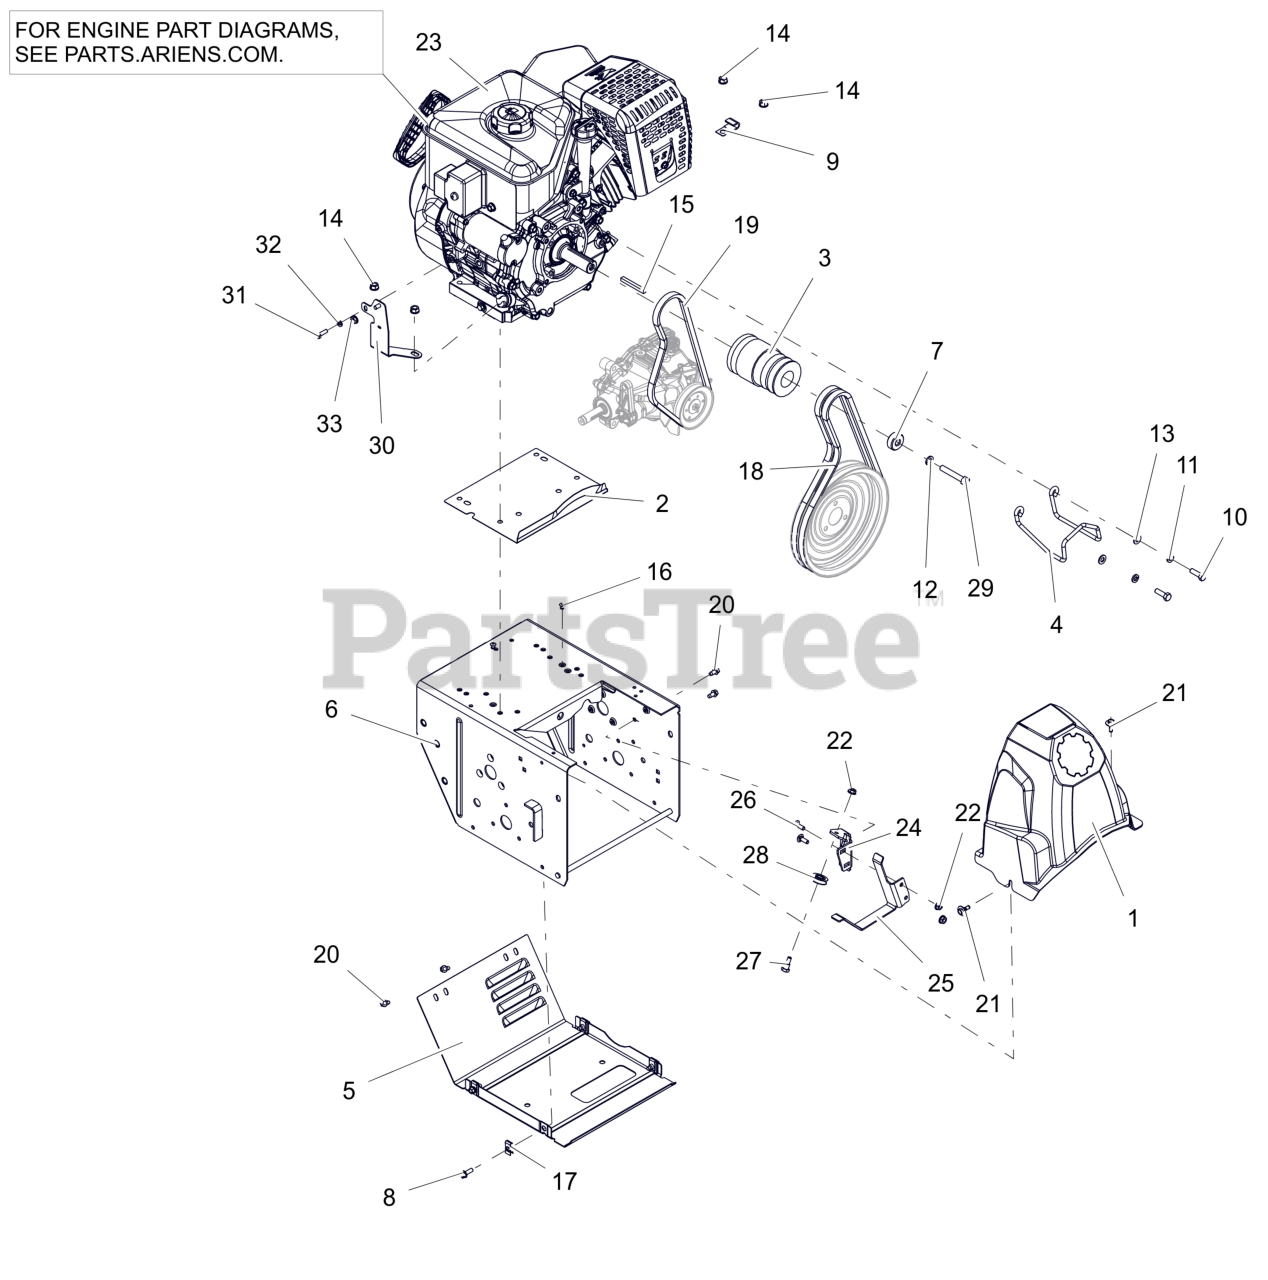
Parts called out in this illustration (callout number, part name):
1	COVER, BELT
2	BAFFLE, WATER - LARGE BLOCK
3	SHEAVE, COMBO HYDRO TRACK 4L
4	FINGER, BELT
5	COVER, BOTTOM - VENTILATED
6	FRAME, MAIN - PRO (WELDMENT)
7	BSHG, SPCR .406 X 1.250 X .500
8	BLT, HWH .25-20X.75 G5 ZCC
9	J-CLAMP
10	BLT, HEX 0.3125-24X1 G5 ZCC
11	WSHR, LK-HVY .312X.097 ZCC
12	WSHR,LK-REG .375X.094 ZCC
13	WSHR,FLT .344X.688X.065 ZCC
14	NUT,LK-CTR-FLG .31-18 GF ZCC
15	KEY .25X.25X2.25
16	RVT, POP .1875 ZCC
17	NUT-RTNR .25-20X.56
18	V-BELT, HA-RAW EDGE (SET)
19	V-BELT, 4L-WRAPPED
20	SCR-TAP .25-20X.50 HWH ZCC
21	SCR-TAP .25-20X.5 CAPTIVE
22	NUT-LK-TOP-FLG .250-20 GF ZCC
23	ENGINE,EFI420 GEN3 120V/60W
24	BRACKET, CLUTCH CABLE
25	FINGER, BELT - FLAT
26	BLT, RHSN .25-20X.750 G5 ZCC
27	BOLT, SHLDR -.375 X .375 X .25-20
28	PULLEY, CABLE
29	BLT, HEX .38-24X2.25 G5 ZCC
30	WLDMT- LG BLOCK FUSE MOUNT
31	BLT,HEX M6-1X20 G8.8 ZC120
32	WSHR,LK-REG .250X.062 ZCC
33	NUT-LK-CTR-FLG .25-20 ZC120
